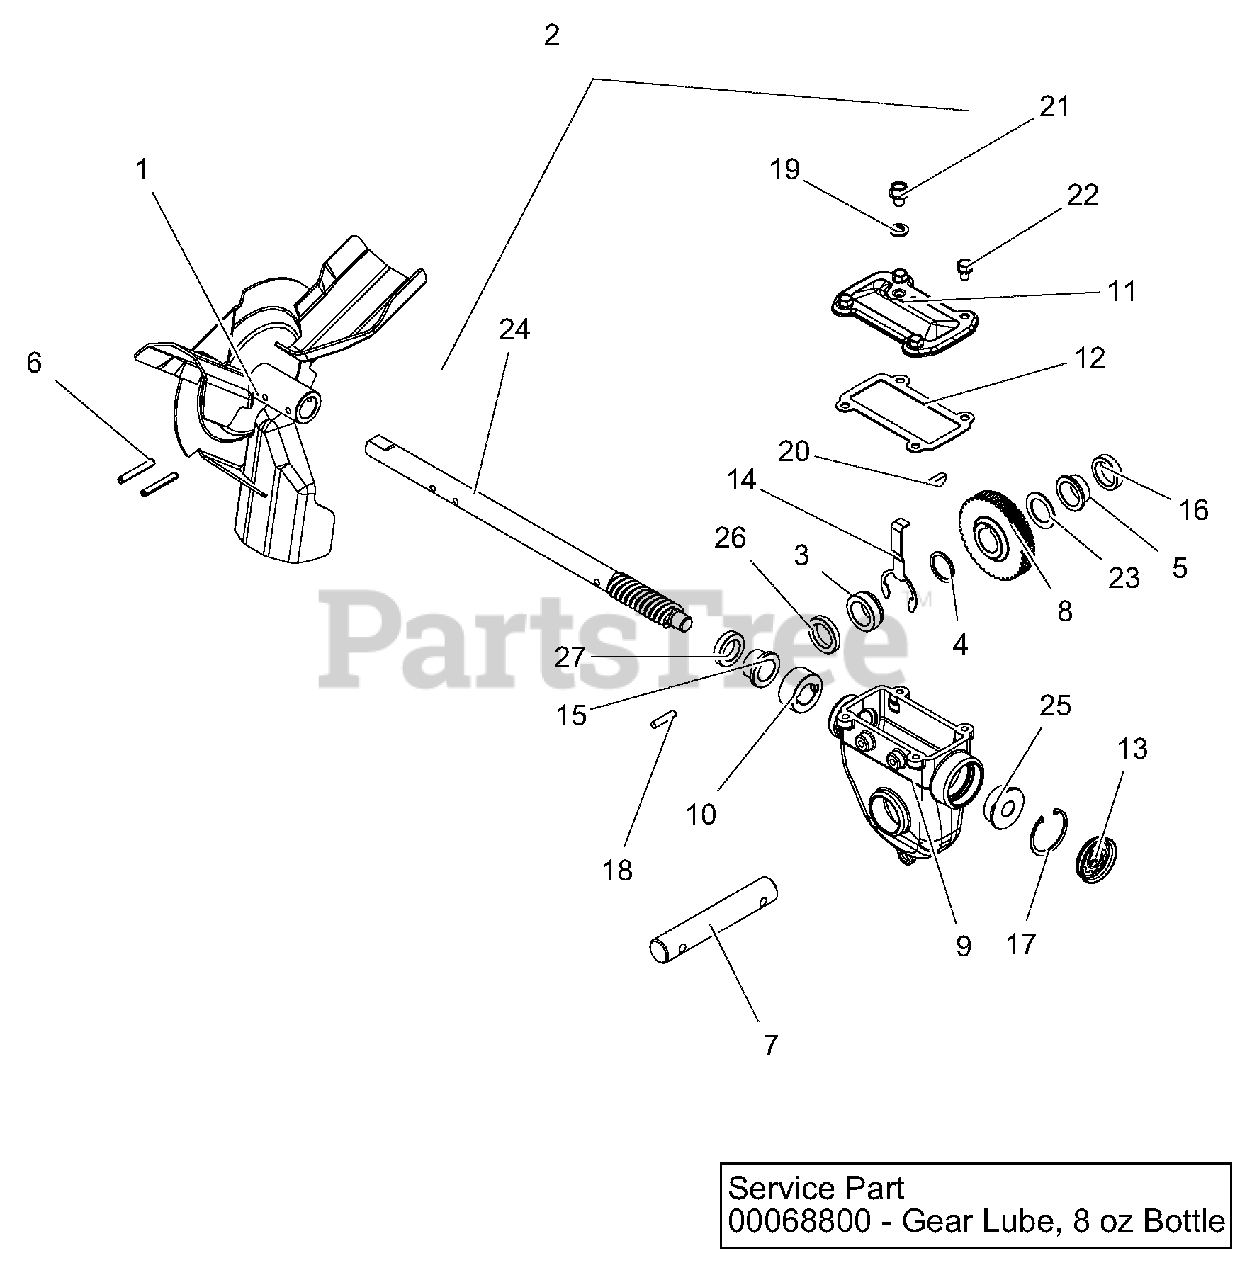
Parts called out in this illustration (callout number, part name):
1	IMPELLER, 3 BLADE-14"
2	GEAR CASE ASSY - DLX IRON
3	BSHG-FLG LARGE, RIGHT
4	WSHR-FL-STL 1.010X1.250X.068YZ
5	BSHG-FLG 1.006X1.128X.555X1.45
6	PIN-ROLL .250X1.75
7	RAKE SHAFT, SHORT-COMMON
8	WORM SHAFT & GEAR
9	GEARCASE, LARGE MACHINED
10	THRUST COLLAR, .875"ID SLIPFIT
11	COVER, TOP - LARGE IRON
12	GASKET, TOP - LARGE GEARCASE
13	COVER, GEAR CASE 1.75"
14	BUSHING RETAINER, LARGE
15	BSHG-FLG .879X1.128X.75X1.45
16	SEAL-OIL .999X1.375X.312 TBC29
17	RG-RTNG-INT 1.750X.062
18	PIN-STR .250X1.12 6150
19	WSHR-BND-SEAL .38X.75X.11 GALV
20	KEY-WDRF .25X.875 HRD #A
21	@SCR-ROLOK .38-16X.50 HWH YWZC
22	BOLT, SEMS .31-18X.50 GR5 YWZC
23	WSHR-FL-STL 1.010X1.505X.062YZ
24	WORM SHAFT & GEAR
25	BSHG-FLG .628X1.503X.58X1.725
26	SEAL-OIL .999X1.500X.250 TBC29
27	SEAL-OIL .873X1.375X.312 TBC29
